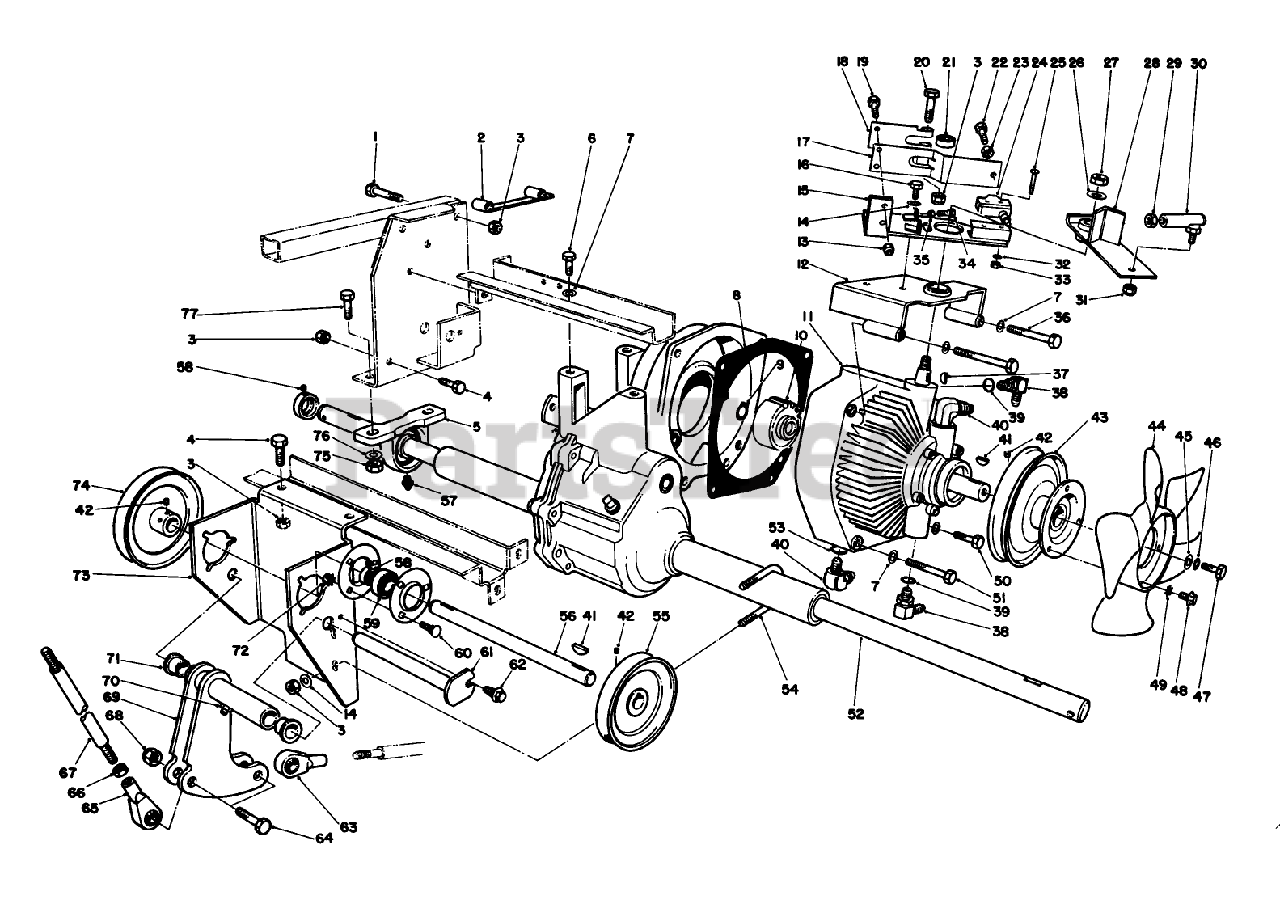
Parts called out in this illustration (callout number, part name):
1	SCREW-HH
3	NUT-LOCK, NI
4	SCREW-HH
6	Screw-Hex Head
7	WASHER-LOCK
9	RING-SNAP, EXTERNAL
10	GEAR-SPUR
11	HYDROSTATIC TRANS.
13	NUT-LOCK, NI
14	WASHER-PLAIN
16	SCREW-HH
17	EXTENDED LEAF SPRING ASM
19	SCREW-HH
20	SCREW-HH
21	BEARING-BALL
22	SCREW-HH
23	NUT-JAM
25	SCREW-MACHINE
26	WASHER-FLAT
27	NUT-HEX
29	NUT-JAM
30	JOINT-BALL
31	NUT-LOCK
32	WASHER-LOCK, INTERNAL
33	NUT-HEX
34	SCREW-HH
35	NUT-JAM
36	SCREW-HH
37	KEY-WOODRUFF
38	FITTING-HYD, 90 DEG
39	O-RING
41	KEY-WOODRUFF
42	SCREW-SET, SQH
43	TRANS PULLEY
45	WASHER-FLAT
46	WASHER-LOCK
47	SCREW-HH
49	WASHER-LOCK, EXT
50	SCREW-HH
51	SCREW-HH
53	O-RING
54	U-BOLT
55	JACKSHAFT INPUT PULLEY
56	JACKSHAFT V
57	FITTING-GREASE
58	SCREW-SET, HSH
60	BOLT-CARR
62	SCREW-HHFTF
63	BALL JOINT LH
64	SCREW-HH
65	BALL JOINT RH
66	NUT-JAM
68	NUT-HEX
69	BELL CRANK ASSY
70	GREASE FITTING
71	BEARING-FLANGE
72	NUT-KEPS
74	JACKSHAFT OUTPUT PULLEY
75	NUT-LOCK, NI
76	WASHER-FLAT
77	SCREW-HH
